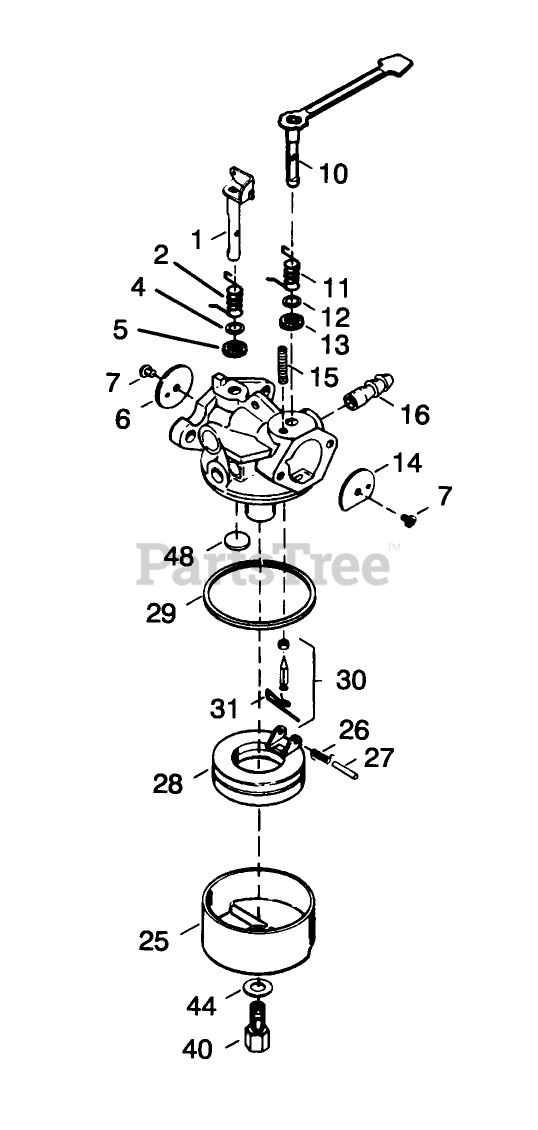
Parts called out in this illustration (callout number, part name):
1	Throttle Shaft Lever Asm.
2	Spring-Trottle, Return
4	Dust Seat Washer
5	Seal-Dust
6	Shutter-Throttle
7	Screw-Shutter
10	Choke Shaft and Lever ASM
14	Shutter-choke
15	Spring-Positioning, Choke
16	Fitting-Fuel
25	Bowl Float
26	Spring-Float, Dampening
27	Shaft-Float
28	Float
29	O Ring-Bowl, Float
30	Inlet Needle, Seat Clip Assy. (Incl. No. 13)
31	Clip-Spring
40	Nut-Float Bowl
44	Gasket-Bowl
48	Plug-Welch, Atmospheric Vent
